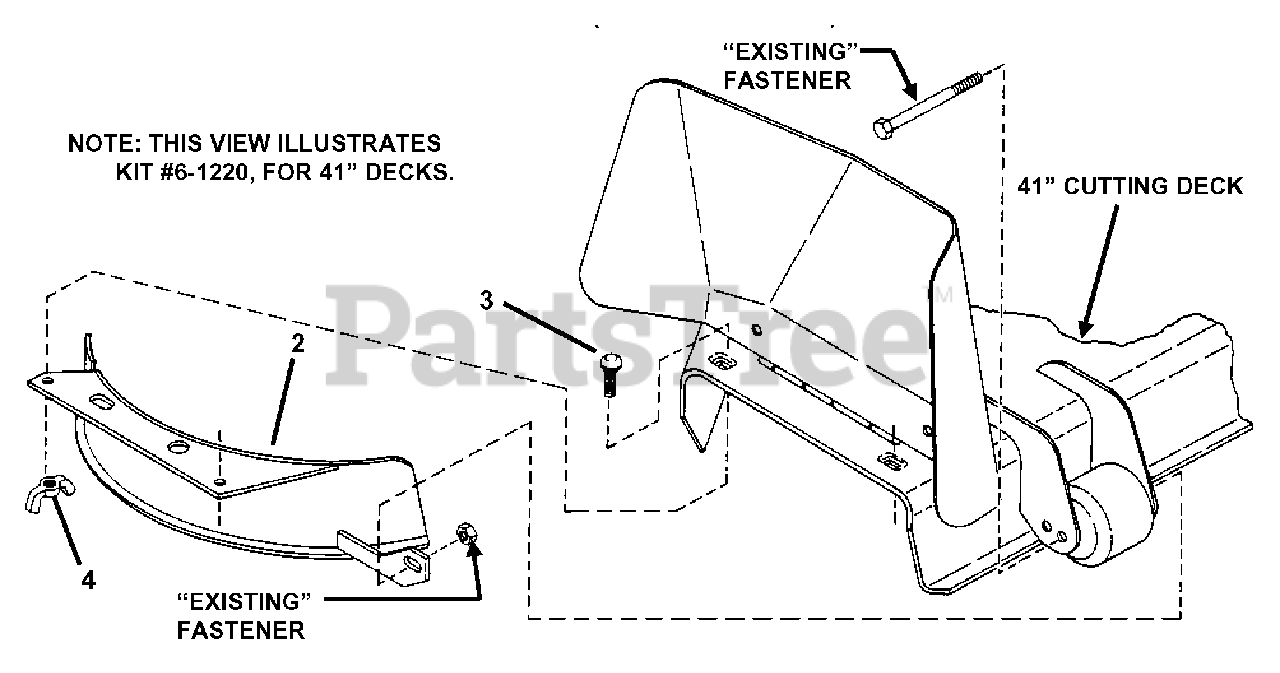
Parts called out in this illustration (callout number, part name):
2	WELDMENT, Mulching Cover, 32"
3	SCREW, 1/2-20 x 3/4" Hex Head Cap
4	NUT, 1/2-20 Hex Jam
